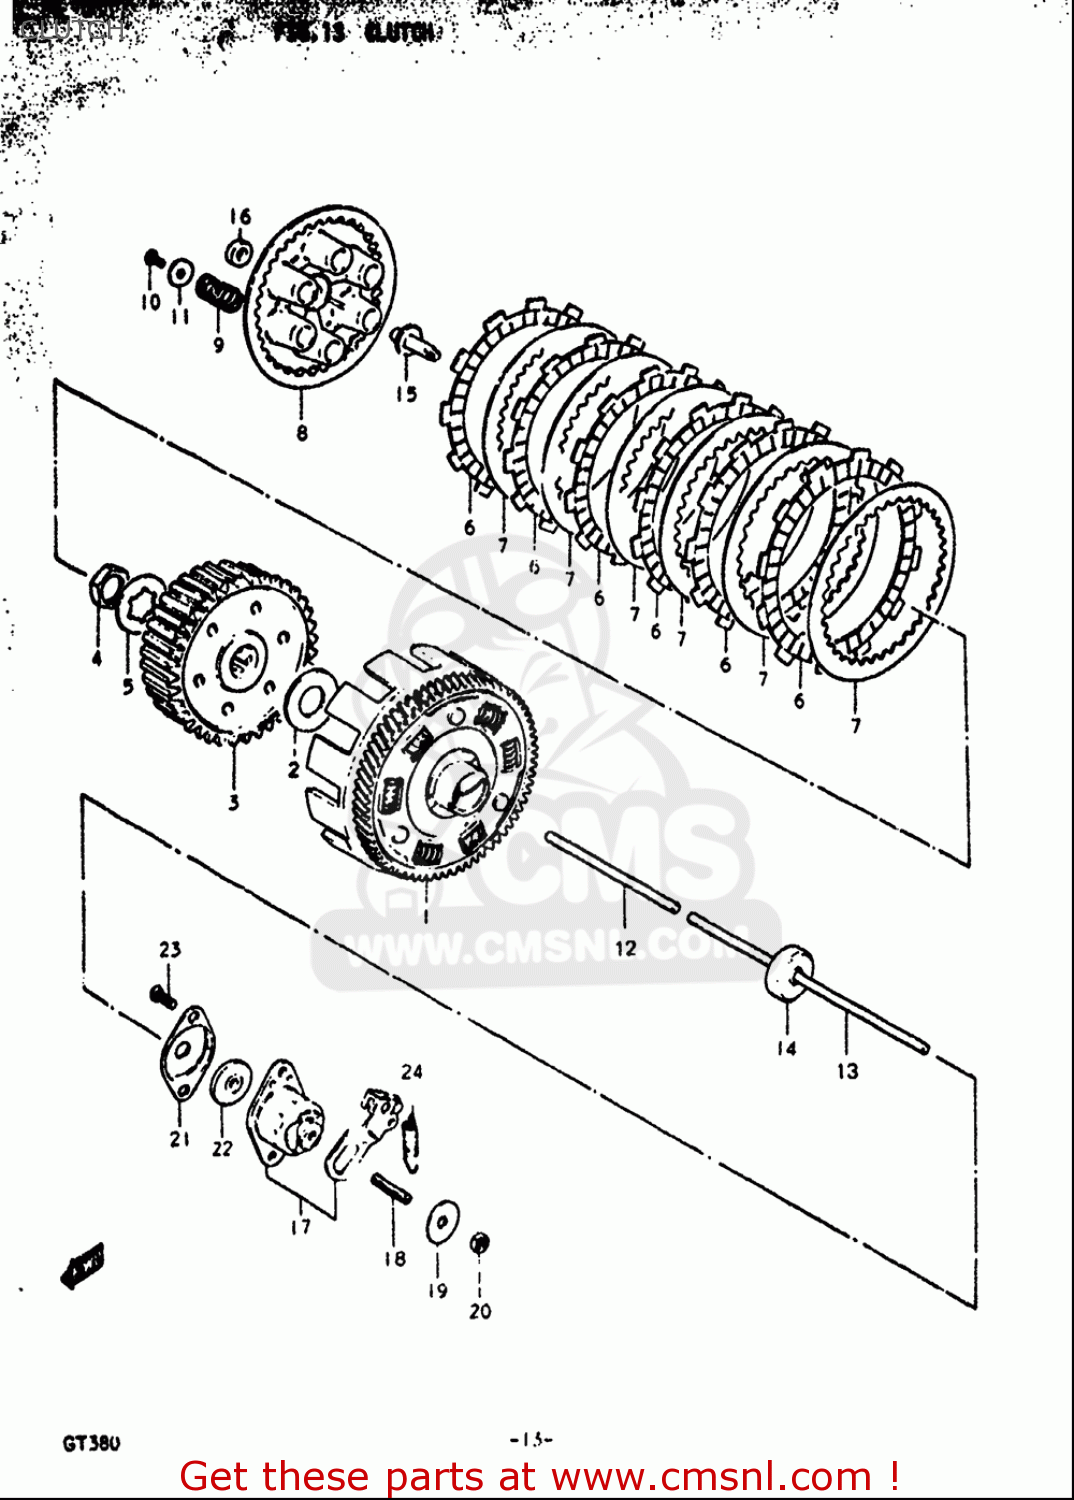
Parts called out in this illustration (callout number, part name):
2	WASHER(20X44X3)
4	NUT
5	WASHER,LOCK
6	PLATE,CLUTCH DRIVE(T:3.5) (NAS)
7	PLATE,CLUTCH DRIVEN(T:2.0) (NAS)
9	SPRING
10	BOLT
11	WASHER(6.5X20X1.6)
12	ROD,CLUTCH PUSH
13	ROD,CLUTCH PUSH NO.2
14	SEAL,OIL (6X30X5)
16	SEAL,OIL (10X17X5)
18	SCREW(6X25)
19	WASHER(6.5X24X1.2)
20	NUT
22	OIL SEAL
23	SCREW
24	SPRING
